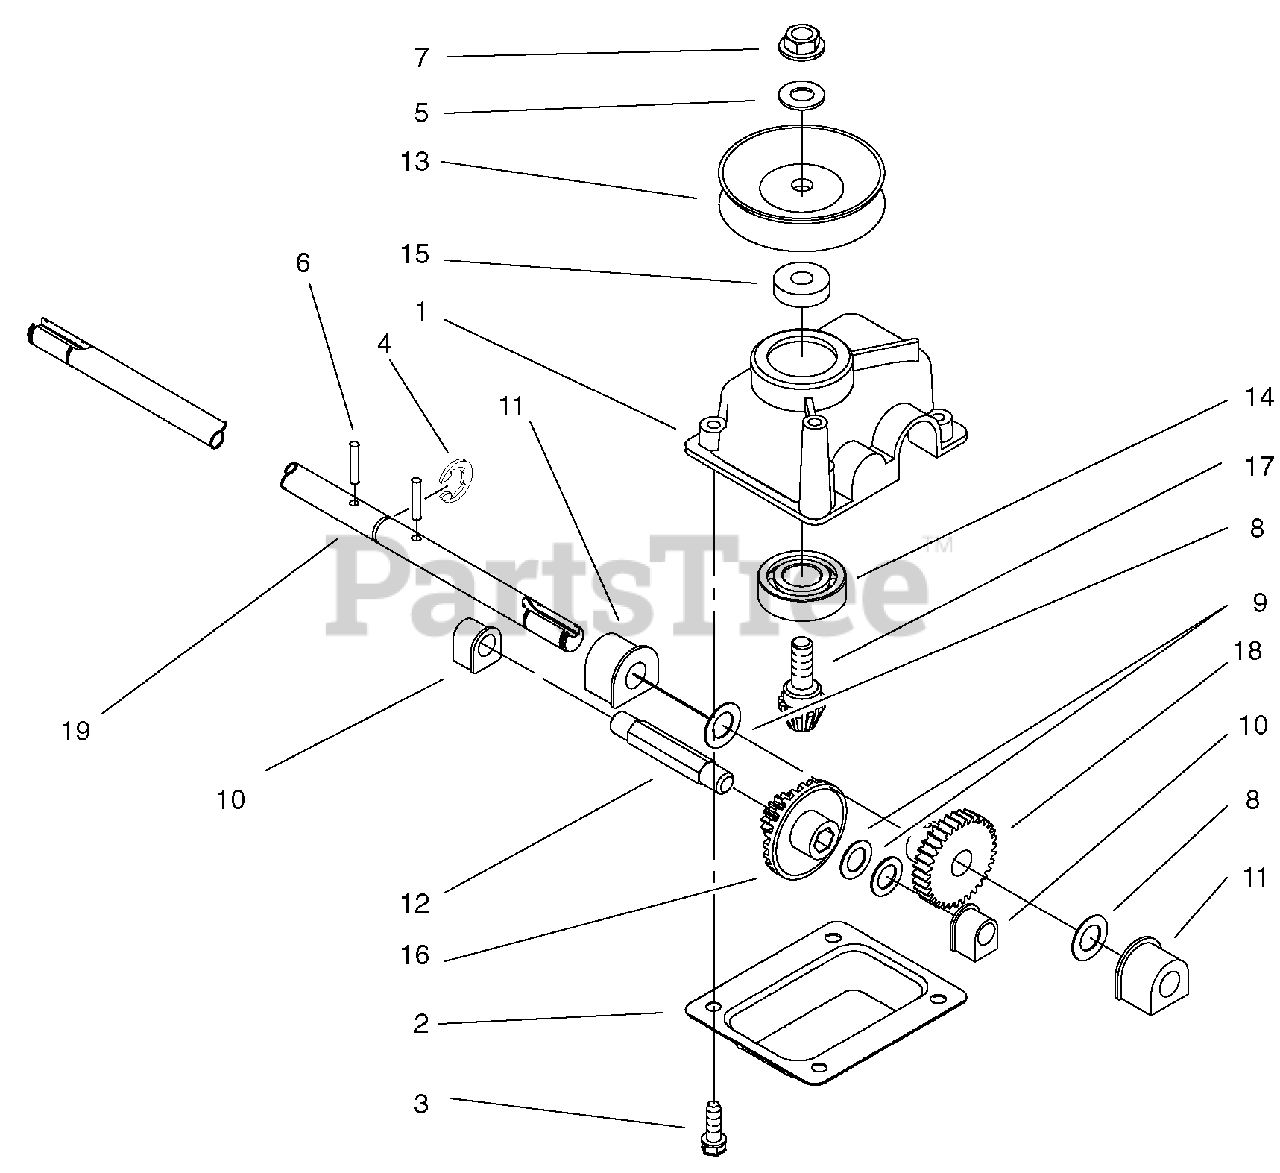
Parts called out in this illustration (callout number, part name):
1	Casting-Gear Case
2	Cover-Gear Case
3	Screw-HWH
4	Ring-Retaining
5	Washer-Flat
6	Pin-Groove
7	Nut-Lock NI
9	Washer-Thrust
11	Bushing-Output
12	Shaft-Intermediate
13	Half-Pulley
14	Bearing-Ball
16	Gear-15t Spur,37t Bevel
17	Gear-Pinion,Bevel
19	Shaft-Output
